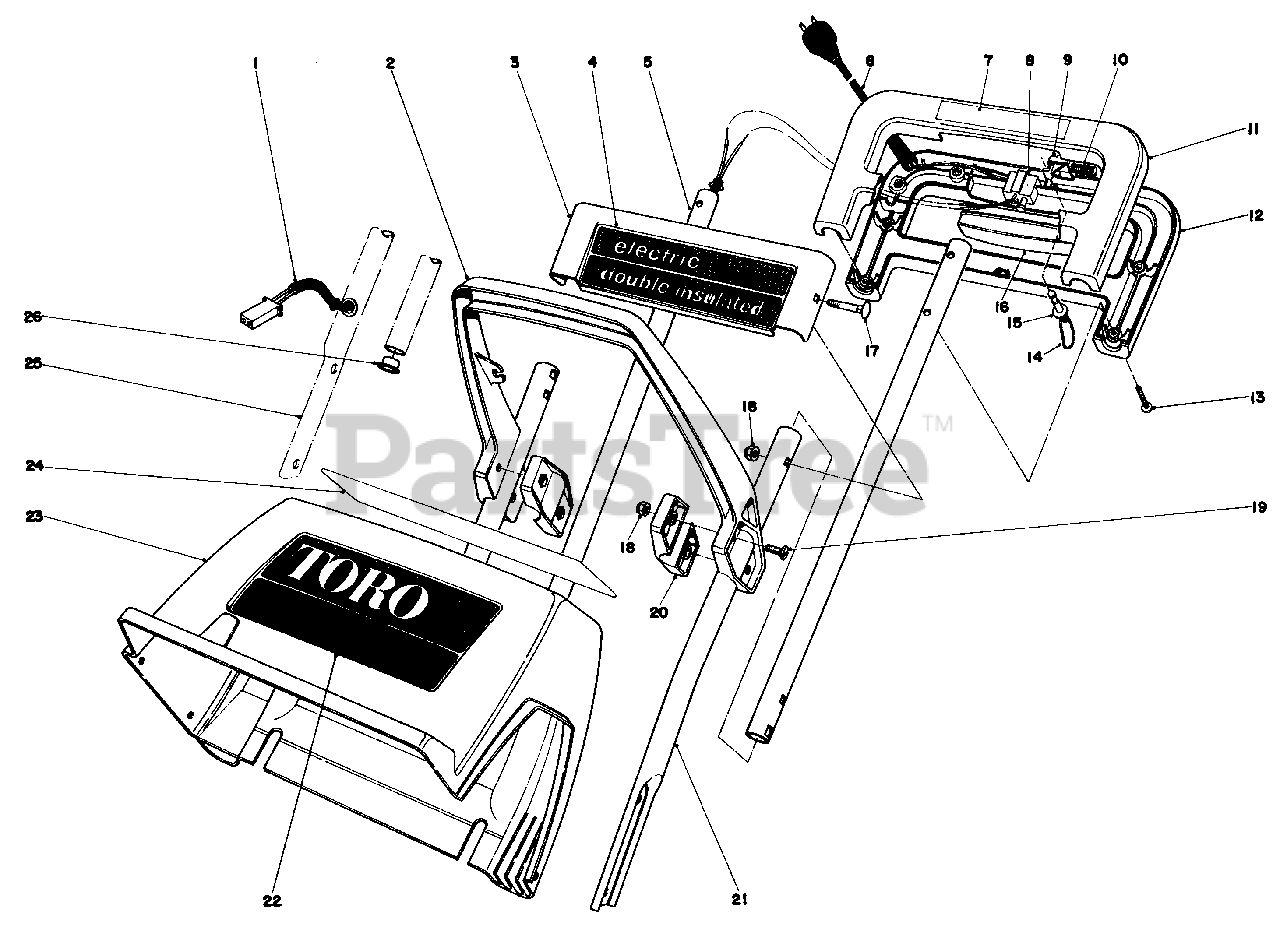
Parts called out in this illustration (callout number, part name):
1	Wire Harness
2	Middle Handle
3	Escutcheon Plate
4	Decal-Electric
5	Upper Tube
6	Cord Supply
7	Decal-Handle
9	Lockout-Switch
10	Spring Compression
11	Handle-Upper Control
12	Handle-Lower Control
13	Screw
14	Key Chain
15	Key
16	Switch Bar
17	Carriage Bolt
19	Screw-Round Head
20	Clamp-Middle Handle
21	Handle-Lower L.H.
22	Decal-Toro S-120
23	Shroud-S-120
24	Decal-U.L.
25	Handle-Lower R.H.
26	Snap Bushing
